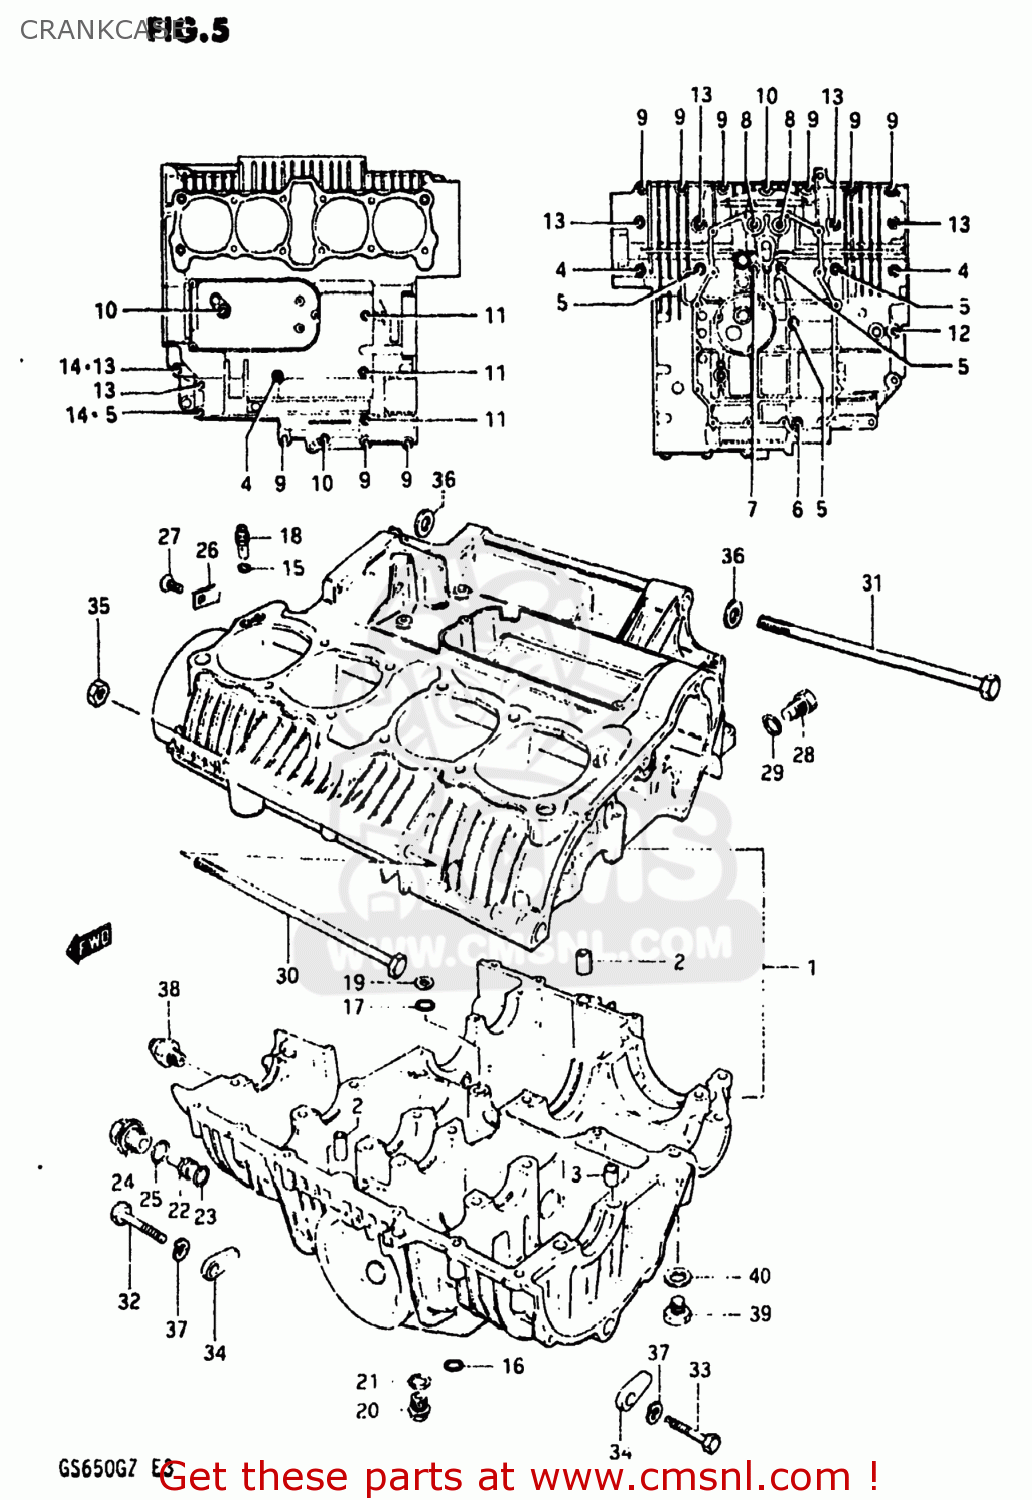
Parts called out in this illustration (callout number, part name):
1	CRANKCASE SET
2	PIN (11X20)(SUS)
3	PIN(10.4X13X22)
4	BOLT
5	BOLT
6	BOLT(8X135)
7	BOLT(8X140)
8	BOLT
9	BOLT
10	BOLT
11	BOLT (6X90)
12	BOLT (8X70)
13	BOLT (8X95)
14	NUT
15	O-RING,OIL GALLERY JET
16	O-RING
17	O RING(D:3.2,ID:12.9)
18	JET(12)
19	WASHER
20	PLUG
21	GASKET(16X22X2) (NAS)
22	PIN,OIL GALLERY
23	SEAL (D:1.9 ID:9.8)
24	PLUG
25	O RING(D:2.4,ID:17.8)
26	PLATE,OIL GALLERY PLUG
27	SCREW
28	PLUG
29	GASKET(12.1X16.2X3.7) (NAS)
30	BOLT
31	BOLT 10X250
32	BOLT 10X55
34	NUT
35	NUT 10MM
36	WASHER
37	LOCK WASHER
38	SWITCH ASSEMBLY
39	PLUG
40	GASKET(14X19.2X2) (NAS)
